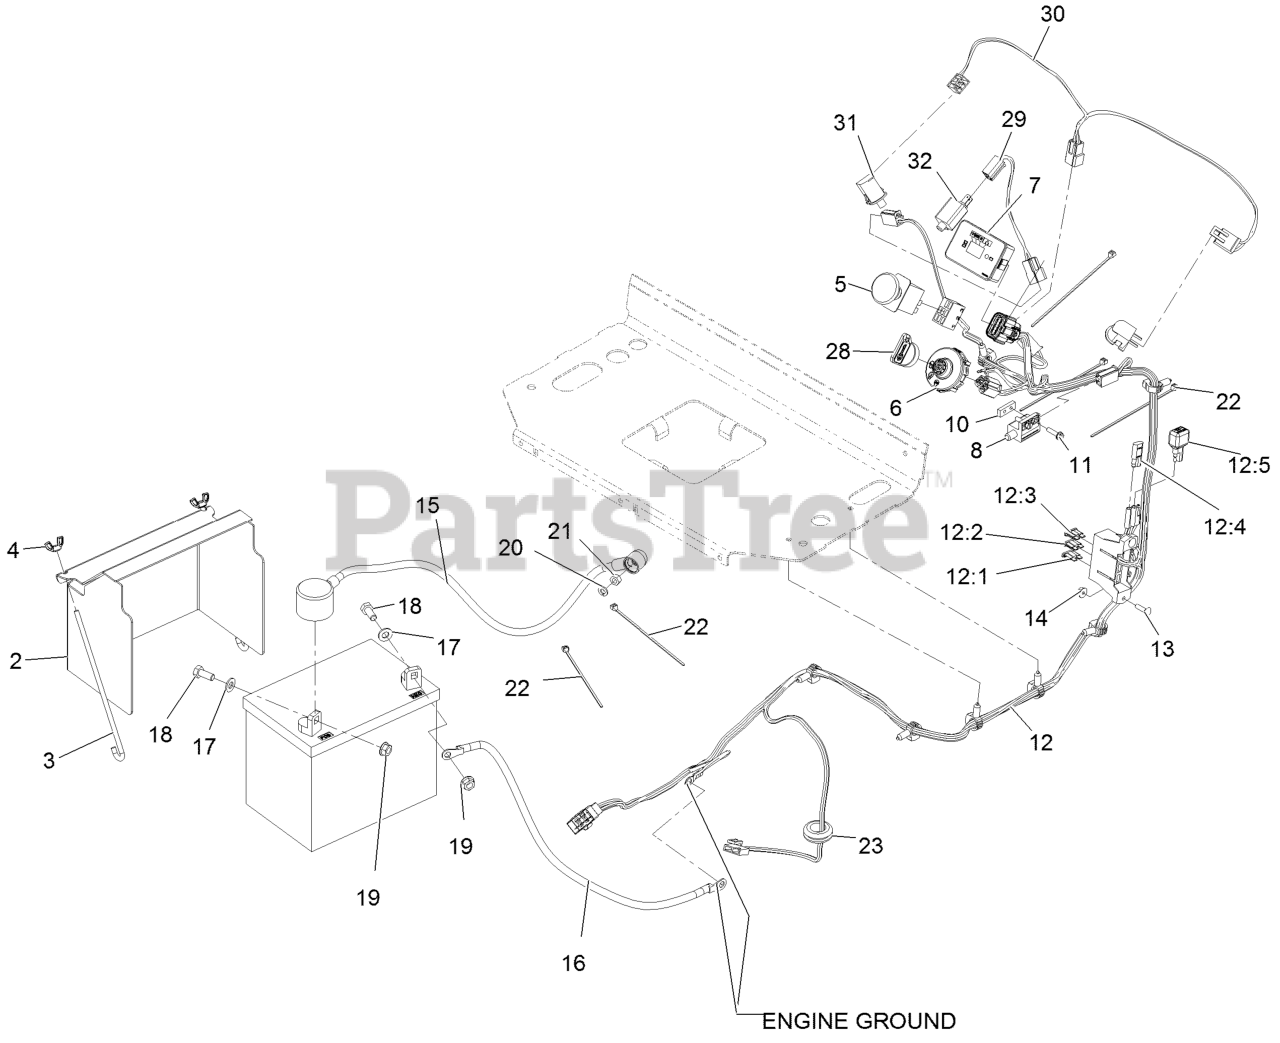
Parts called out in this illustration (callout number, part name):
2	COVER-BATTERY
3	BOLT-HOLDDOWN
4	WINGNUT
5	SWITCH-PTO, ON-ON
7	MODULE-HOUR METER
8	SWITCH-CLOSED, NORMALLY
10	PLATE-TAPPED
11	SCREW-HWH
12	HARNESS-WIRE
12:1	FUSE-BLADE, 30 AMP
12:2	FUSE-BLADE, 25 AMP
12:3	FUSE-BLADE, 10 AMP
12:4	CAP-PLUG
13	SCREW-CARR
15	CABLE-BATTERY, POSITIVE
16	CABLE-BATTERY, BLACK
17	WASHER-PLAIN
18	SCREW-HH
19	NUT-HHF, SMOOTH
20	SCREW-HH
21	NUT-HEX
22	TIE-CABLE
23	GROMMET
28	KEY-IGNITION
29	HARNESS-NEUTRAL
30	HARNESS-OPC
31	SWITCH-BAIL
32	SWITCH-OPEN, NORMALLY
